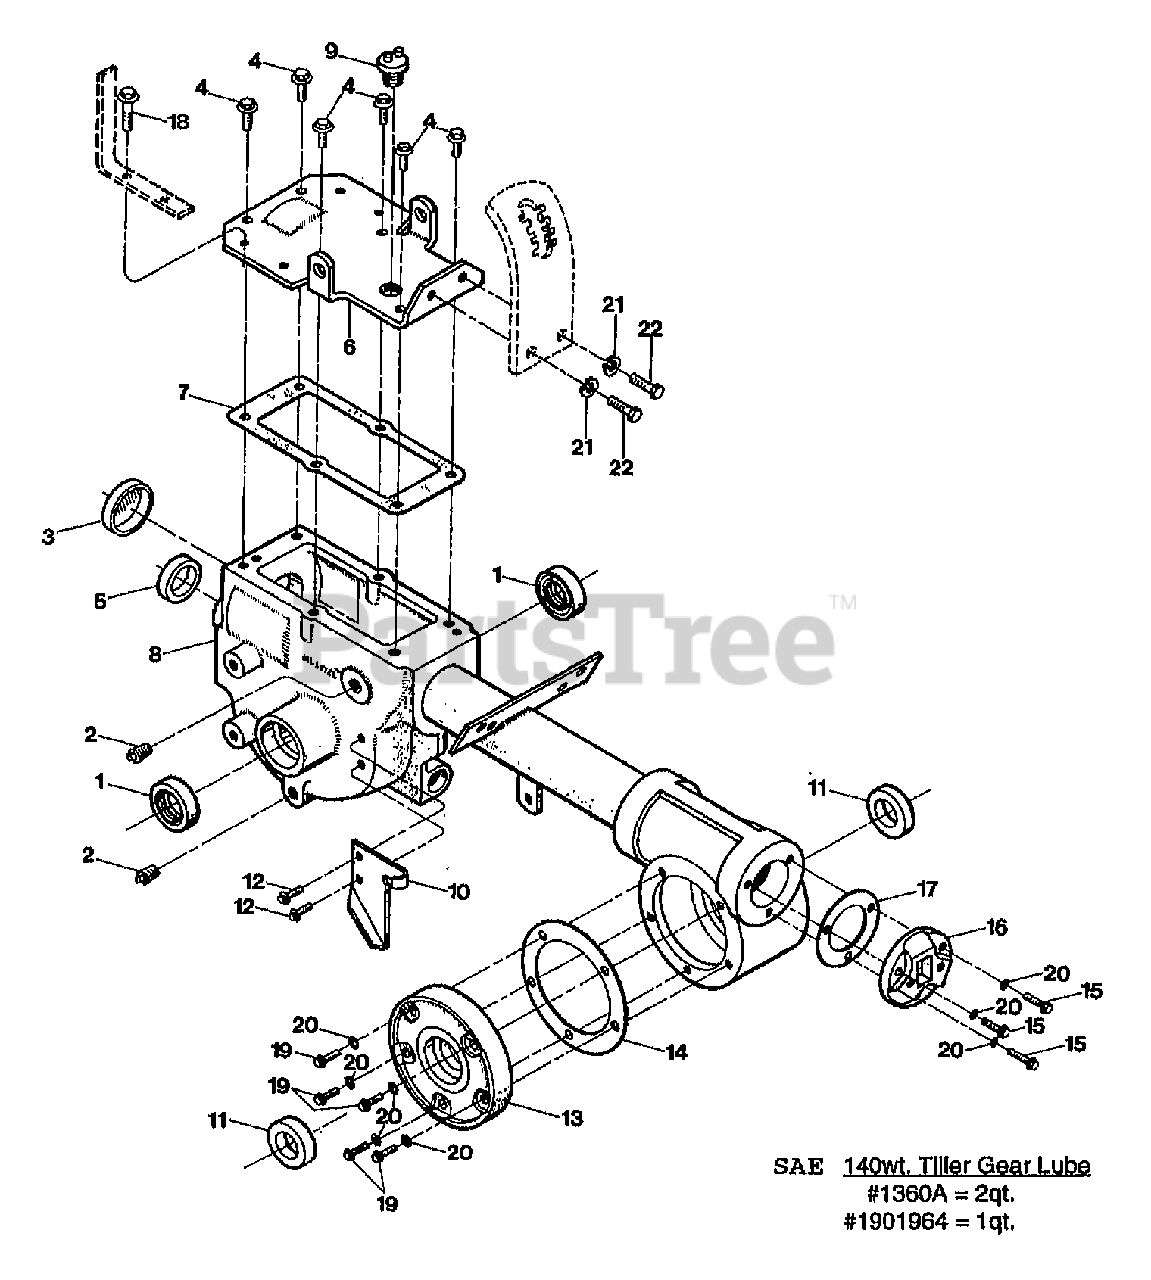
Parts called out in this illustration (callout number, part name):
1	SEAL-OIL WHEELSHAFT
2	PLUG-PIPE 1/4 NPT
3	SEAL-BORE
4	SCR-HFLK 5/16-18X.75 ZP
5	SEAL-PINION SHAFT PT/85030/00
6	KIT-COVER TRANS W/HDW (INCL. FOUR #18, TWO EACH OF #21 & 22)
7	GASKET-TRANS COVER
8	ASSM-TRANS A-UNIT P/ECHO
9	PLUG-OIL FILL 3/4-10
10	PLATE-CABLE MT PNT
11	SEAL-TILLER SHAFT
12	SCR-HFLK 5/16-18X.62 G5ZP
13	COVER-TILLER HSG MACH (INCL. FIVE SCREWS, #19)
14	GASKET-TILLER COVER (FITS ALL COVERS)
15	SCR-HFLK 1/4-20X.875
16	CAP-REAR #1115
17	GASKET-BRG COVER
18	SCR-HFLK 5/16-18X1.00 ZP
19	SCR-HH 1/4-20X.625
20	WASHER - NYLON, NOT REUSABLE
21	WASHER-LK .375 @ DEPL
22	SCR-HH 3/8-16X.75 G5 ZP
